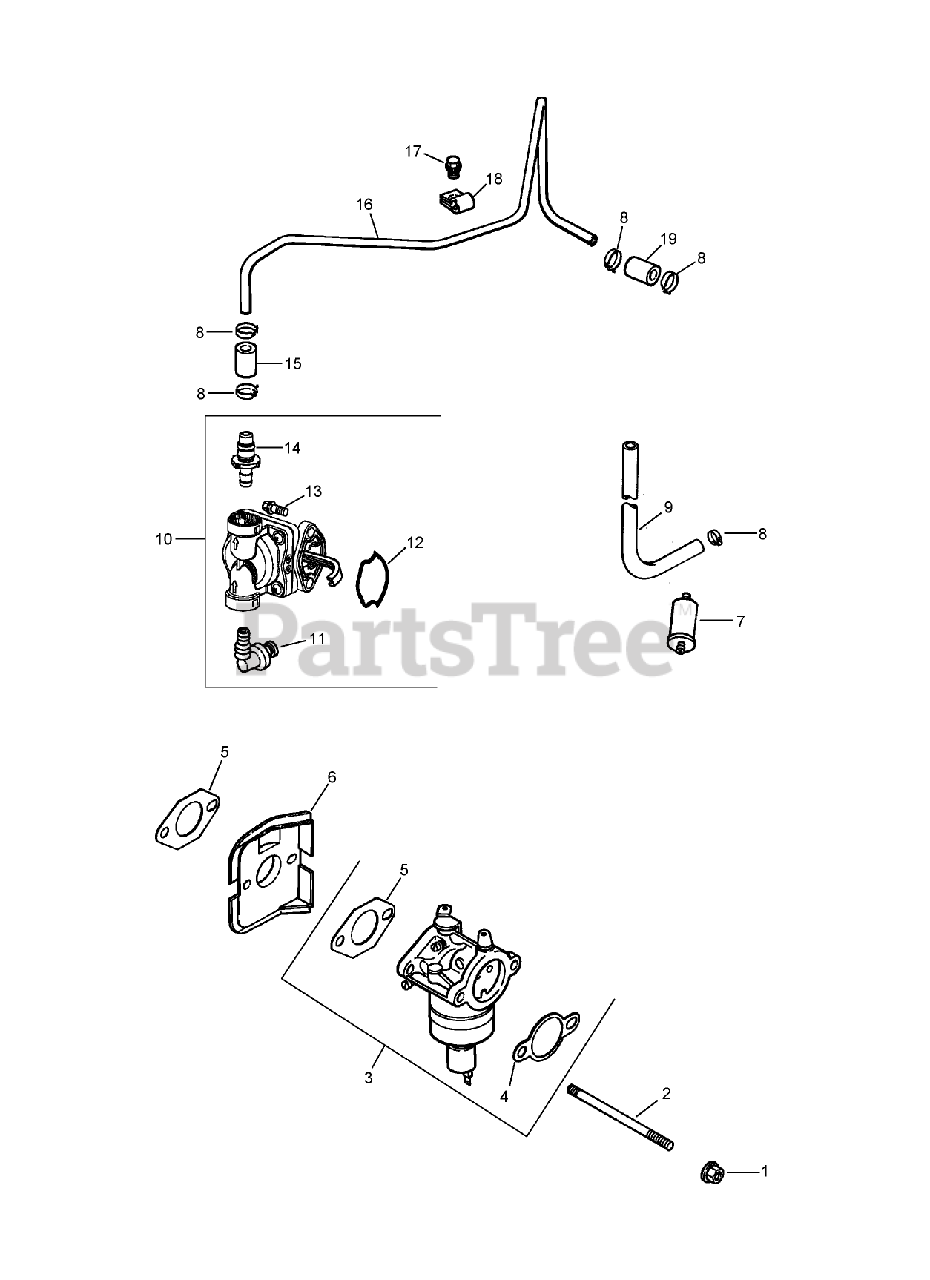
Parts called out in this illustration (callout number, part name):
1	NUT-FLANGE (M6X1.0)
2	Stud (M6x1.0x116)
3	carburetor Kit (Incl. Ref. No. 4, 5, qty. 1], Tie 12 454 03-S, and Terminal 25 452 20-S)
4	Gasket-Base, Air Cleaner
5	Gasket-Carburetor
6	Deflector-Heat
7	Filter-Fuel
8	CLAMP-HOSE, SPRING (1/2)
9	Line-Fuel, 8in
10	Fuel Pump Kit (Incl. Ref. No. 11-14)
11	Fitting-90 DEG
12	O-Ring (Fuel Pump)
13	Screw-Socket, 6 Lobed (Thread Forming, M6x1.0x20)
14	Fitting-Straight
15	Line-Fuel (1-1/4in)
16	Line-Fuel. Metal
17	SCREW-HHFTF (M5X.80X10)
18	CLAMP-INSULATED
19	Line-Fuel (2-1/2in)
